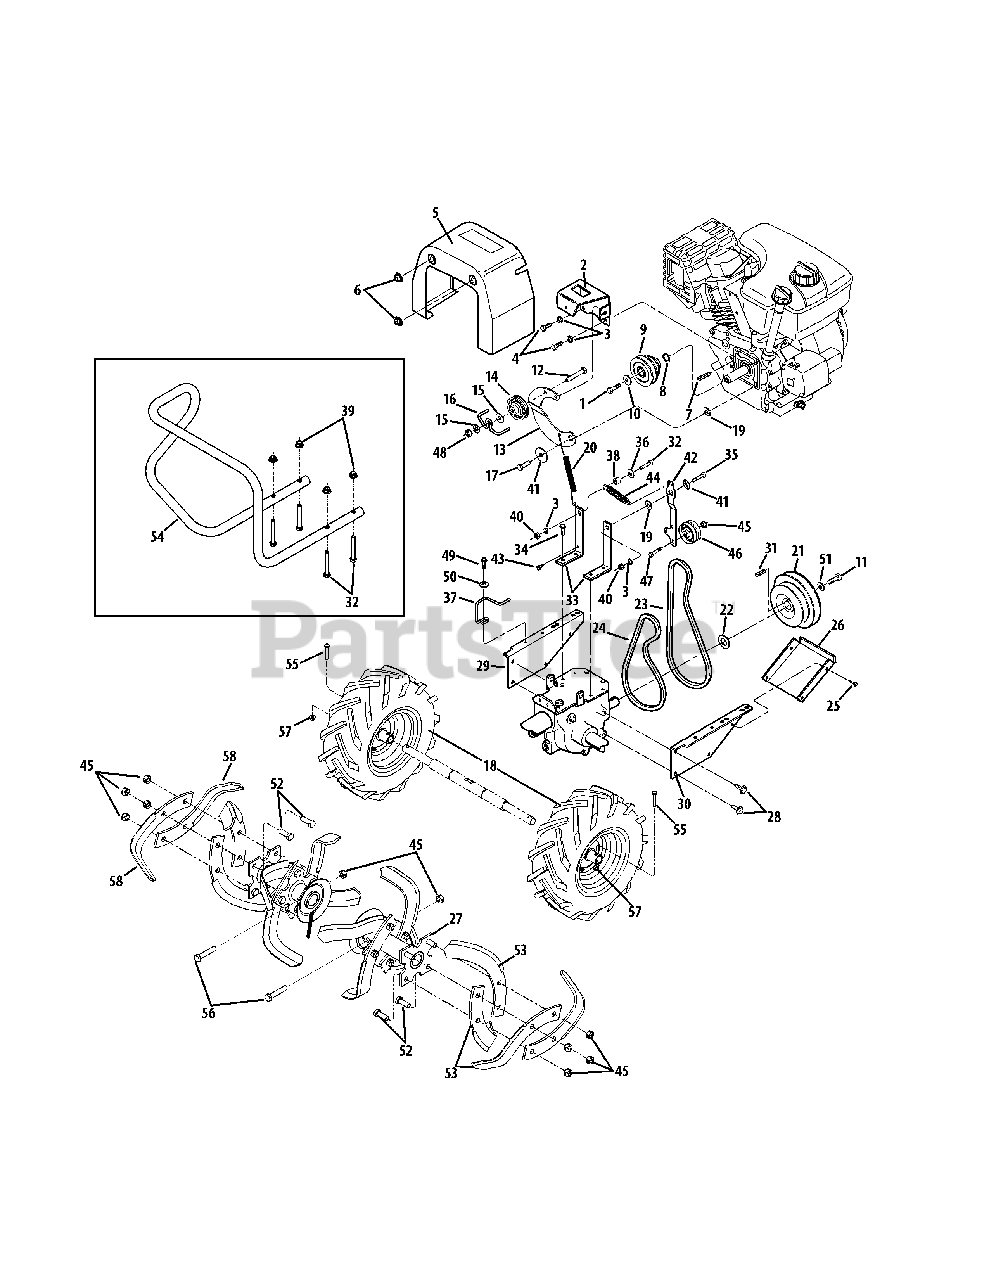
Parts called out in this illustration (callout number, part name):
1	Hex Screw, 3/8-24 x 2.25
1	Screw, 5/16-24 x 1.125
2	Clutch Cable Bracket
3	Lockwasher, 5/16
4	Hex Head Screw, 5/16-24 x 1/2
6	Flange Lock Nut, 5/16-18
7	Key, 3/16-2
7	Key, 3/16 x 1.5
9	Engine Pulley
10	Washer, .344 x 1.0 x .063
10	Washer .827 x .331 x .098
11	Hex Head Screw, 5/16-24 x 1-1/8
12	Hex Head Screw, 5/16-18 x 2
13	Reverse Idler Arm
14	Reverse Idler Pulley
15	Flat Washer, 5/16
16	Wire Formed Belt Guide
17	Hex Head Screw, 5/16-24 x 1
18	Wheel Assembly, 13 x 5 x 6
19	Flat Washer, 1-1/8
20	Reverse Return Spring
21	Transmission Pulley
22	Support Washer
23	Reverse Clutch Belt
24	Forward Clutch Belt
25	Self-tapping Screw, #10-32 x 1/2
26	Belts/Pulleys Guard
28	Hex Flange Screw, 5/16-18 x 3/4
29	Engine Support Bracket (left side)
30	Engine Support Bracket (rt side)
31	Key, 3/16 x 1.50
32	Hex Head Screw, 5/16-18 x 2-1/4
33	Mounting Bar
34	Hex Flange Screw, 5/16-18 x .75
35	Hex Head Screw, 5/16-18 x 1-1/2
36	Flat Washer, 5/16
37	Belt Guide
38	Pivot Bushing
39	Hex Lock Nut, 5/16-18
40	Hex Nut, 5/16-18
41	Shoulder Washer
42	Forward Tiller Direction Idler Arm
43	Self-tapping Screw, #10-24
44	Spring
45	Hex Locknut, 5/16-18
46	Forward Idler Pulley
47	Screw, 3/8-16 x 1-3/4
48	Hex Lock Nut, 5/16-18
49	Screw, 1/4-20 x 3/4
50	Flat Washer, 1/4
51	Belleville Washer, .827 x .331 x .098
52	Hex Head Screw, 3/8-16 x 1
53	Bolo Tine-single (Left)
55	Hex Head Screw, 1/4-20 x 1.5
56	Hex Head Screw, 3/8-16 x 2
57	Flange Hex Locknut, 1/4-20
58	Bolo Tine-single (Right)
